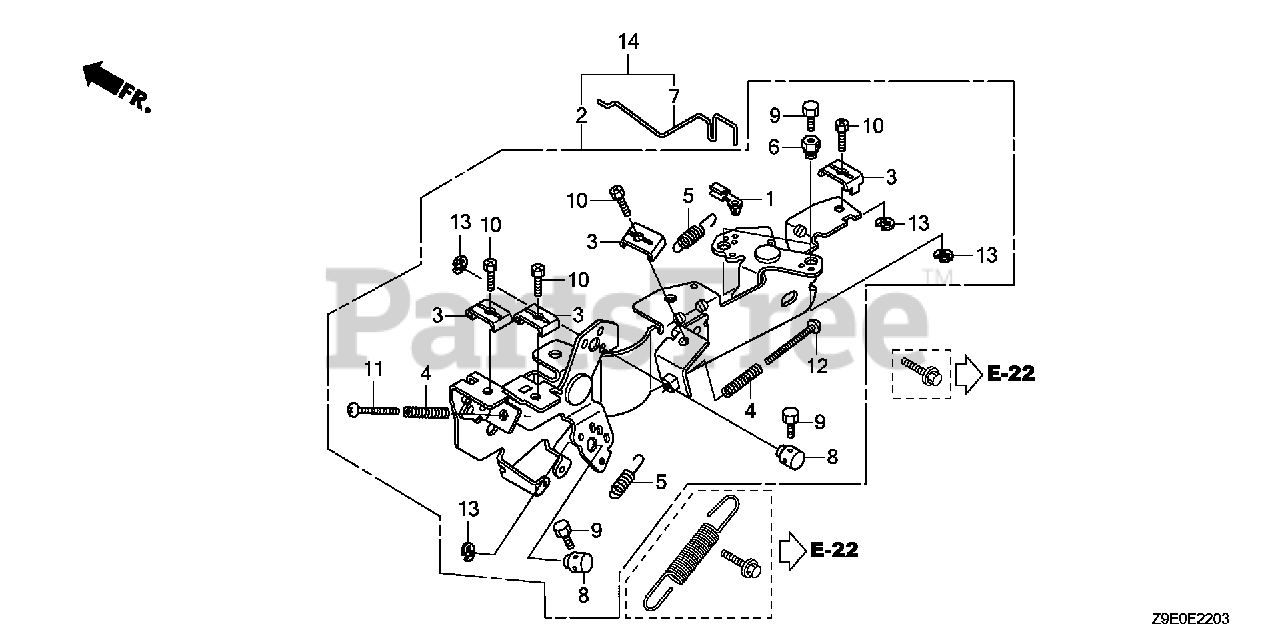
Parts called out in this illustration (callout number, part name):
1	JOINT, ROD
2	CONTROL ASSY.
3	HOLDER, CABLE
4	SPRING, CONTROL ADJUSTING Use from Engine SN 2327377.
5	SPRING, CABLE RETURN
6	HOLDER, WIRE
7	ROD, CHOKE CONTROL
8	HOLDER, CABLE
9	BOLT, RECESSED (4X6)
10	BOLT, RECESSED (5X16)
11	SCREW, PAN (5X30)
12	SCREW, PAN (5X45)
13	E-RING (5MM)
14	CONTROL KIT
